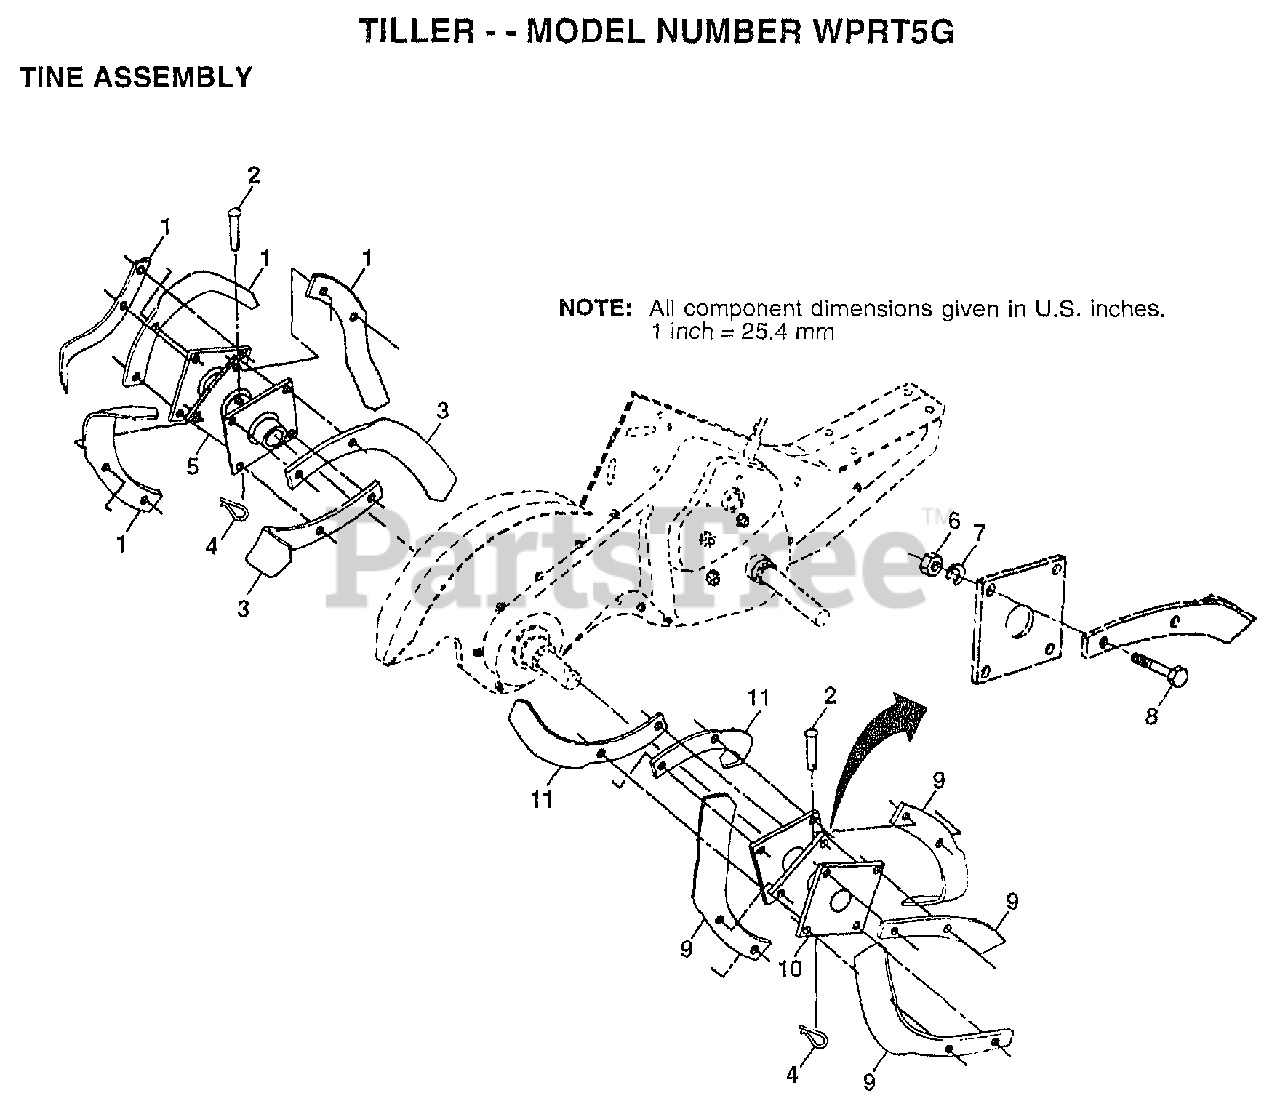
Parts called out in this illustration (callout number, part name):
2	PIN.CLEVIS.SHEAR
3	"TINE.LH.12"""
4	RETAINER.SPRING
5	HUB&PLATE ASM LH
7	LOCKWASHER
8	BOLT
10	HUB&PLATE ASM RH
11	"TINE.RH.12"""
